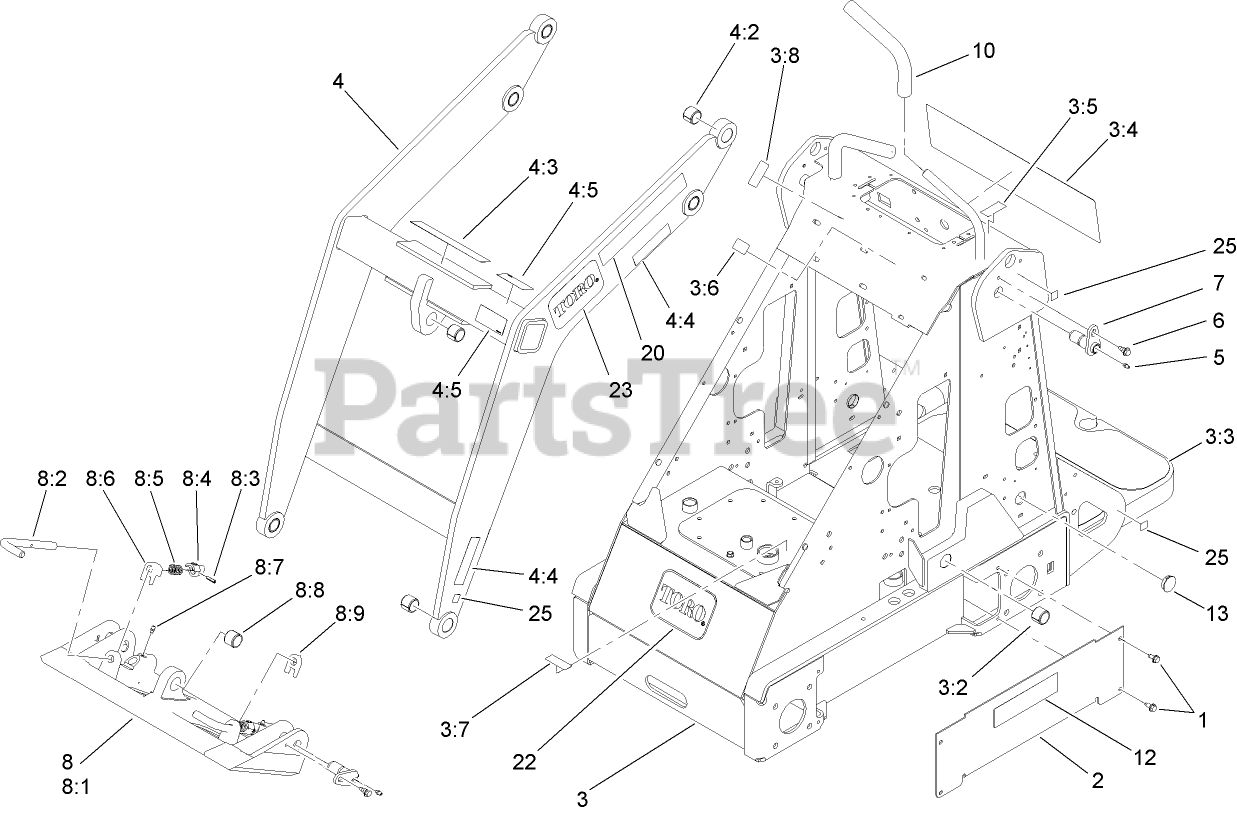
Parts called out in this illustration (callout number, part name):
1	SCREW-HWHTF
2	COVER-HOSE
3	FRAME ASM
3:2	BUSHING-TENSION
3:3	TREAD-FOOT
3:4	DECAL-CONTROL PANEL, CE
3:5	DECAL-THROTTLE
3:6	DECAL-LIMITER, SPEED
3:7	DECAL-OIL, HYD
3:8	DECAL-SELECTOR
4	LOADER ASM
4:2	BUSHING-TENSION
4:3	DECAL-CAUTION
4:4	DECAL-WARNING, PINCH
4:5	DECAL-NO RIDER
5	FITTING-GREASE
6	BOLT-SHOULDER
7	PIN-PIVOT
8	QUICK ATTACH ASM
8:1	MOUNT-ATTACH, QUICK
8:2	PIN-LOCKING
8:3	PIN-GROOVED
8:5	SPRING-COMPRESSION
8:6	STOP-RH
8:7	FITTING-GREASE
8:8	BUSHING-TENSION
8:9	STOP-LH
10	GRIP-CUSHION
13	PLUG-HOLE
20	DECAL
22	DECAL
23	DECAL
25	DECAL-POINT, LIFT
